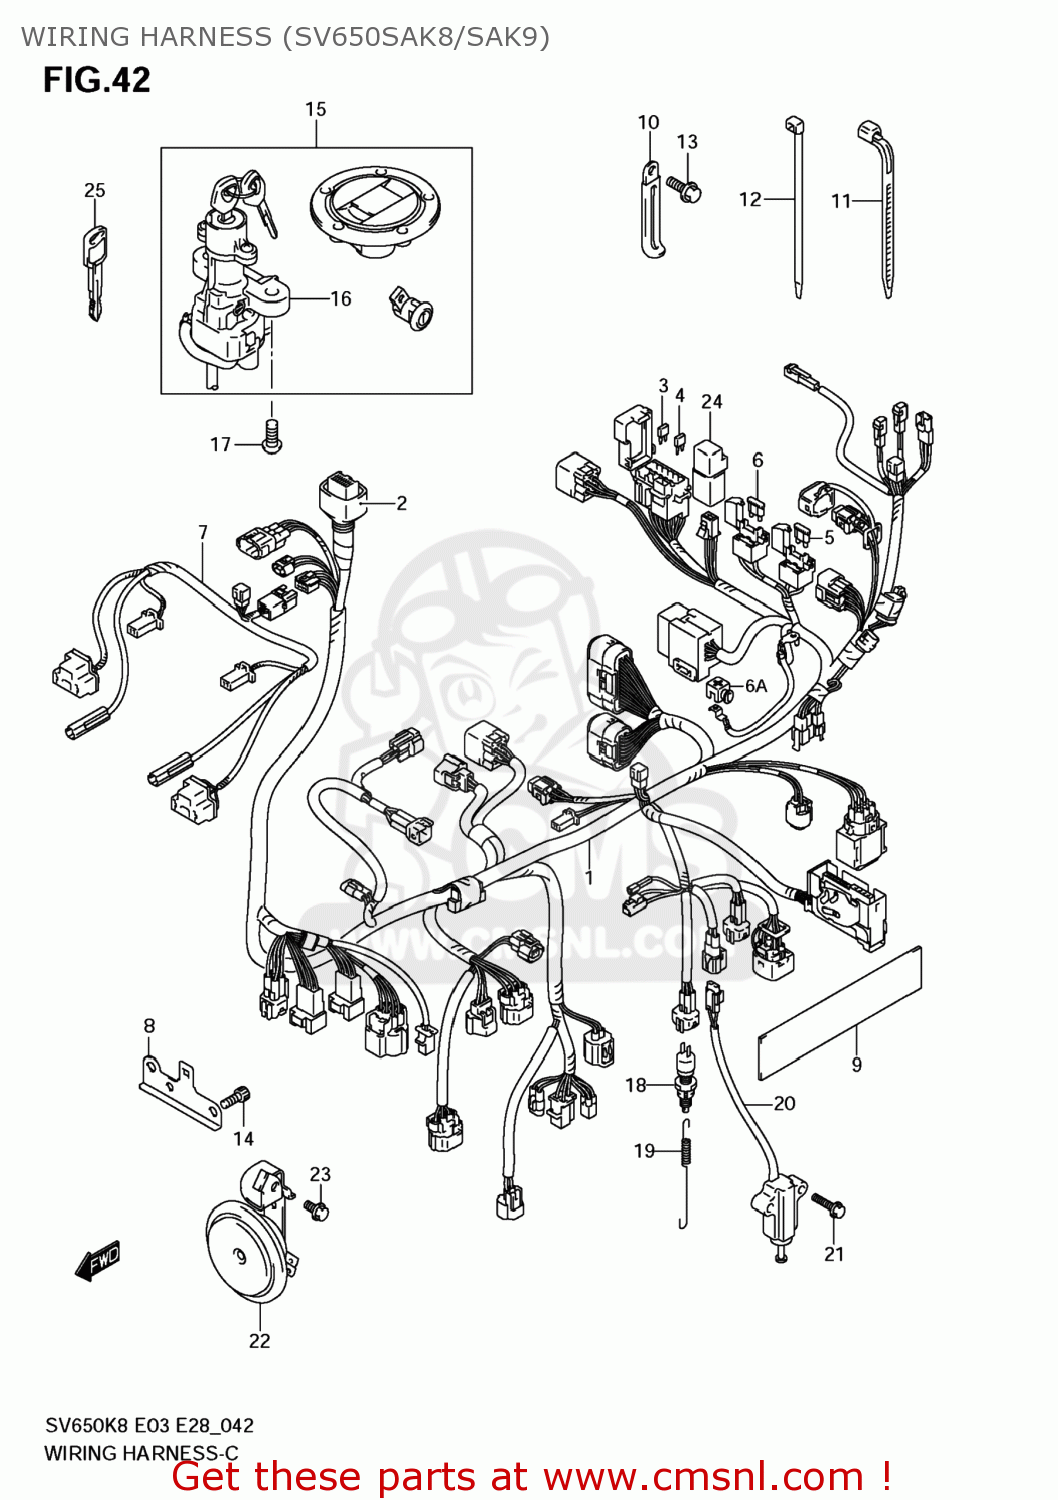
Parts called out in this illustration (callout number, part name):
1	KABELBOOM
2	COVER,SPEEDOMETER COUPLER
3	FUSE(10A)
4	FUSE(15A)
5	FUSE (25A)
6	FUSE(40A)
6A	CAP,BATTERY PLUS
7	HARNESS,WIRING NO.2
8	HOLDER,COUPLER
9	PROTECTOR(20X90)X1.0
10	CLAMP(L:45)
11	CLAMP(L:95)
12	CLAMP(L:145)
13	BOLT
14	BOLT
15	LOCK SET
16	LOCK ASSY,STEERING
17	BOLT(8X20)
18	SWITCH ASSY,STOP LAMP
19	SPRING
20	SWITCH ASSY,SIDE STAND
21	BOLT
22	HORN ASSY
23	BOLT
24	RELAY ASSY
25	KEY,BLANK
